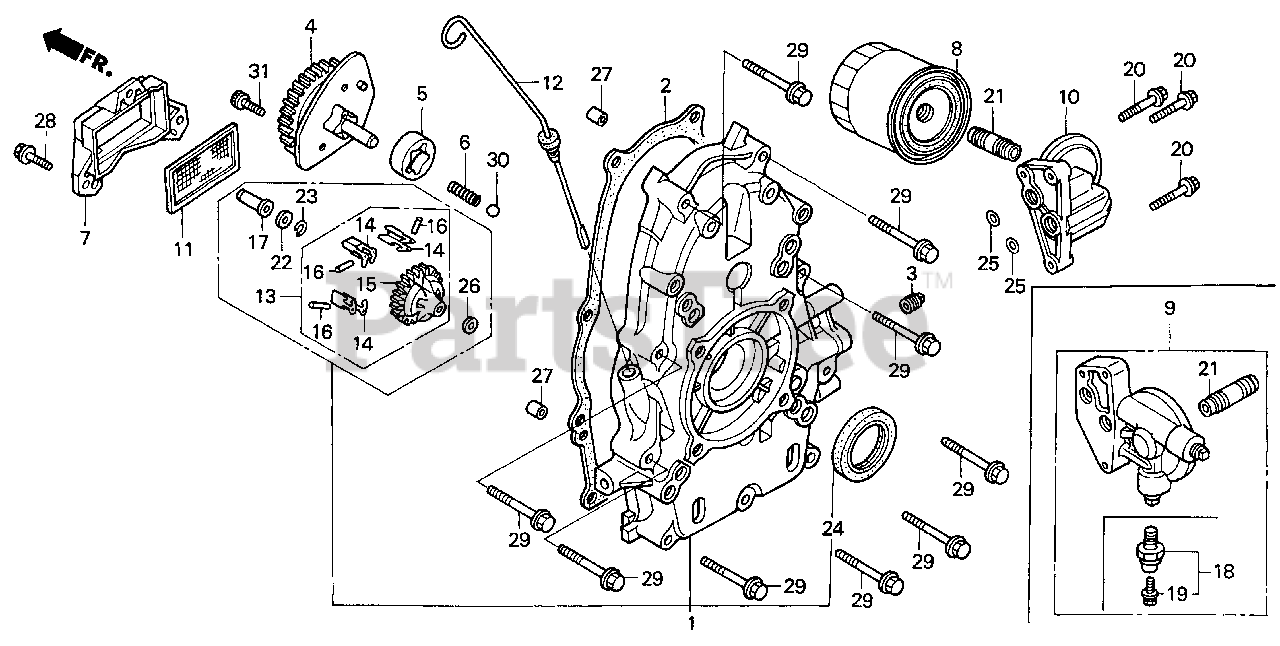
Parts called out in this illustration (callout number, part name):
1	COVER ASSY., CRANKCASE (Q-TYPE)
2	GASKET, CASE COVER
4	COVER ASSY., OIL PUMP
5	ROTOR, OIL PUMP (OUTER)
6	SPRING, RELIEF VALVE
7	COVER, OIL FILTER
8	FILTER, OIL (TOYO ROKI) (SOLD IN MULTIPLES OF 30)
8	FILTER, OIL (SOLD INDIVIDUALLY)
10	BASE, OIL FILTER
11	SCREEN, OIL FILTER
12	DIPSTICK, OIL
13	GOVERNOR ASSY.
14	WEIGHT, GOVERNOR
15	HOLDER, GOVERNOR WEIGHT
16	PIN, GOVERNOR WEIGHT
17	SLIDER, GOVERNOR
20	BOLT, FLANGE (6X28)
21	HOLDER, OIL FILTER
22	WASHER (6X16)
23	CLIP, GOVERNOR HOLDER
24	OIL SEAL (38X58X9)
25	O-RING (11.8X2.4)
26	WASHER, PLAIN (6MM)
27	PIN A, DOWEL (8X14)
28	BOLT, FLANGE (6X20)
29	BOLT, FLANGE (8X50)
30	BALL, STEEL (#12) (3/8)
31	BOLT, SOCKET (6X16)
